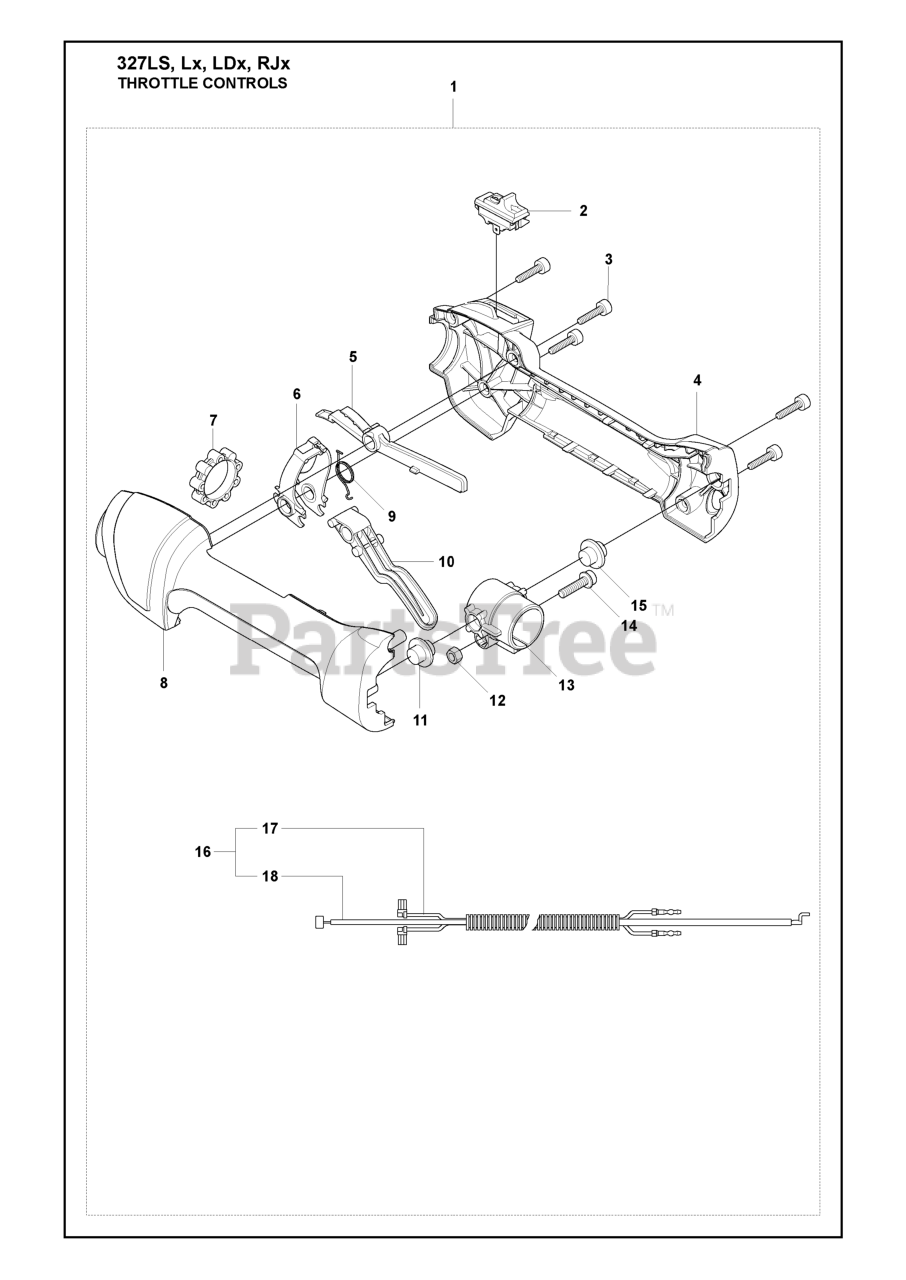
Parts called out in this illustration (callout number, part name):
1	ASSY THROTTLE CONTROL
2	STOP BUTTON
5	THROTTLE LOCK
7	VIBRATION DAMPER
9	RETURN SPRING
10	THROTTLE TRIGGER
11	VIBRATION ABSORBER
15	VIBRATION ABSORBER
17	SHORT CIRCUIT CABLE
18	THROTTLE WIRE ASSY
